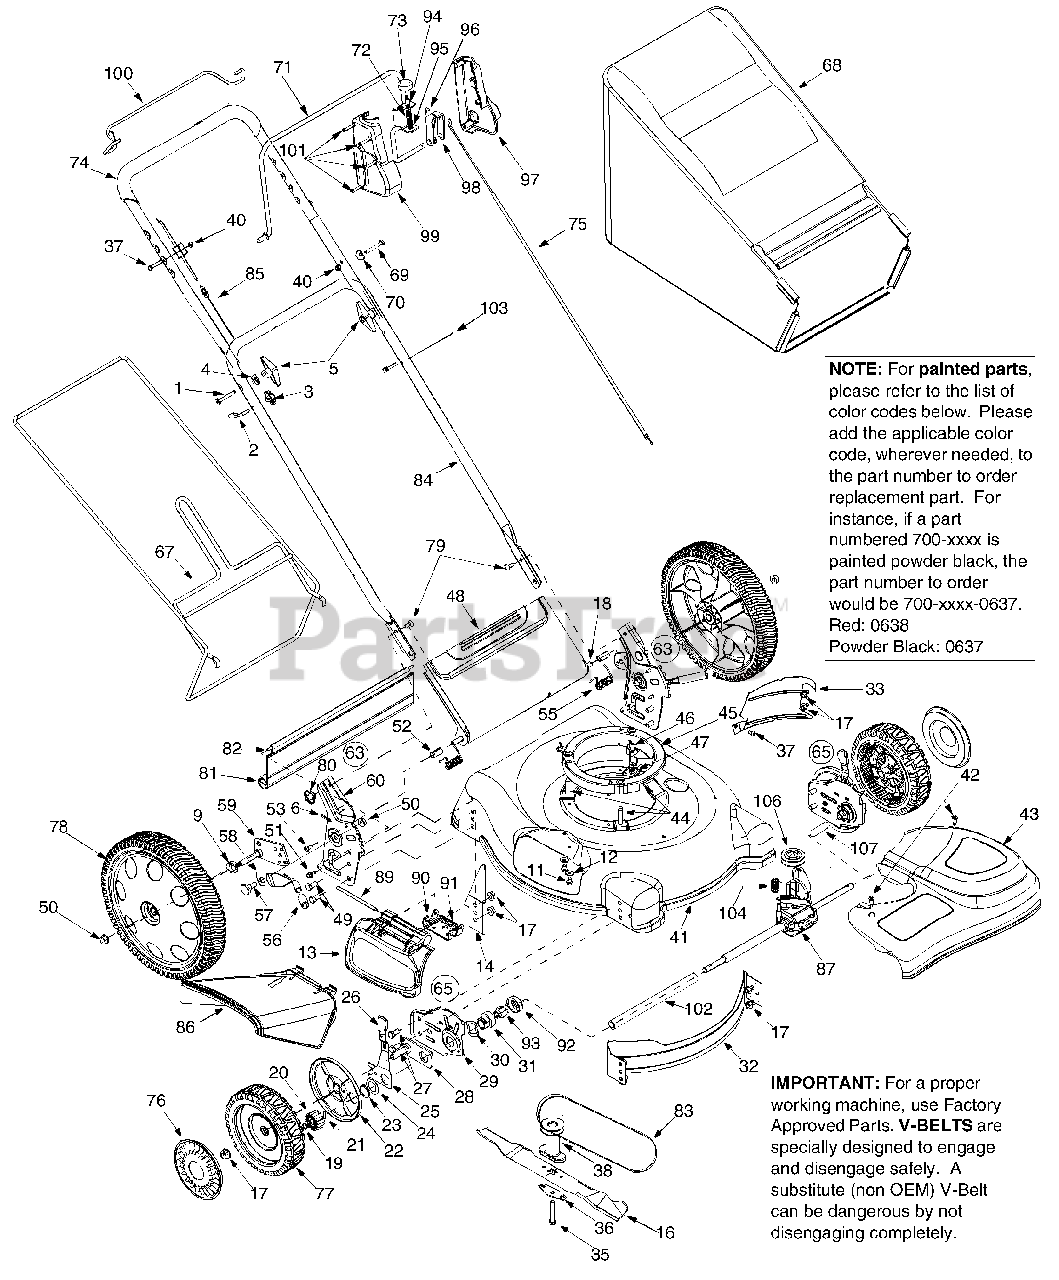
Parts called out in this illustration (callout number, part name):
1	Carriage Bolt
2	Rope Guide
4	Saddle Washer
5	Handle Knob
6	Hairpin Clip
9	Spring Wash. .500 I.D. x 1.00 O.D.
10	Bell Washer .375 I.D. x .870 O.D.
11	TT Screw 1/4-20 x .500
12	Bell Wash. .265 I.D. x .75 O.D.
13	Mulching Plug (Hinged)
15	Mulching Plug
16	Mulching Blade w/Star
17	Flanged Lock Nut 3/8-16
18	Pivot Rod: Chute Door
19	Snap Ring
20	Gear 14T RH
20	Gear 14T LH
21	Dowel Pin
22	Wheel Dust Cap
23	Snap Ring
24	Washer DD 1.5" O.D.
25	Adj. Lever Assembly LH: Front
25	Adj. Lever Assembly RH: Front
26	Knob
27	Hex Screw
28	Pivot Plate Assembly
30	Wave Washer
31	Bearing Support
36	Blade Bell Support
37	Hex Screw 1/4-20 x 1.5"
38	Blade Adapter/Pulley
40	Hex Lock Nut
41	Rear Dischage Deck 21"
42	Shld. Screw
43	Transmission Cover
44	TT Sems Screw
45	Engine Spacer Assembly
46	Belt Keeper Pin
47	Hex Nut 1/4-20
48	Grassbag Door - Plastic
49	Hex Hd. Cap Scr. 3/8-16
50	Flange L-Nut 3/8-16
51	AB Tap Screw 1/4-14 x .625"
52	Spacer
53	Pan Hd. Screw 1/4-20 x .5"
54	Pivot Rod
55	Torsion Spring RH
55	Torsion Spring LH
56	Foam Grip
57	Shoulder Screw
58	Spring Lever
59	Pivot Bar Assembly LH
59	Pivot Bar Assembly RH
60	Handle Bracket Assembly RH
60	Handle Bracket Assembly LH
62	AB Screw 1/4-14 x 0.625"
63	Handle Brkt. Ass'y Comp. RH
63	Handle Brkt. Ass'y Comp. LH
65	Height Adjuster Ass'y Comp. RH
65	Height Adjuster Ass'y Comp. LH
68	Grass Bag
69	Hex Hd. Cap Screw
70	Saddle Washer
72	Compression Spring
76	Hub Cap
77	Wheel 8 x 2.125
78	Wheel 14 x 2.125
79	Carriage Bolt
80	Wing Nut
81	Trail Shield
82	Wire
83	V-Belt
85	Drive Cable
86	SD Chute Deflector
87	Transmission Assembly Comp.
89	Hinge Pin
91	Torsion Spring
92	Bearing Retainer
93	Bearing Sleeve .50 I.D.
95	Retention Ring
96	Torsion Spring
97	Control Cover LH
99	Control Cover RH
101	Hi-Low Screw
102	Sleeve Spacer 10.1" Lg.
103	Cable Tie
104	Belt Tension Spring
105	Engine Shroud
106	Input Pulley
107	Sleeve Spacer 2.1" Lg.
